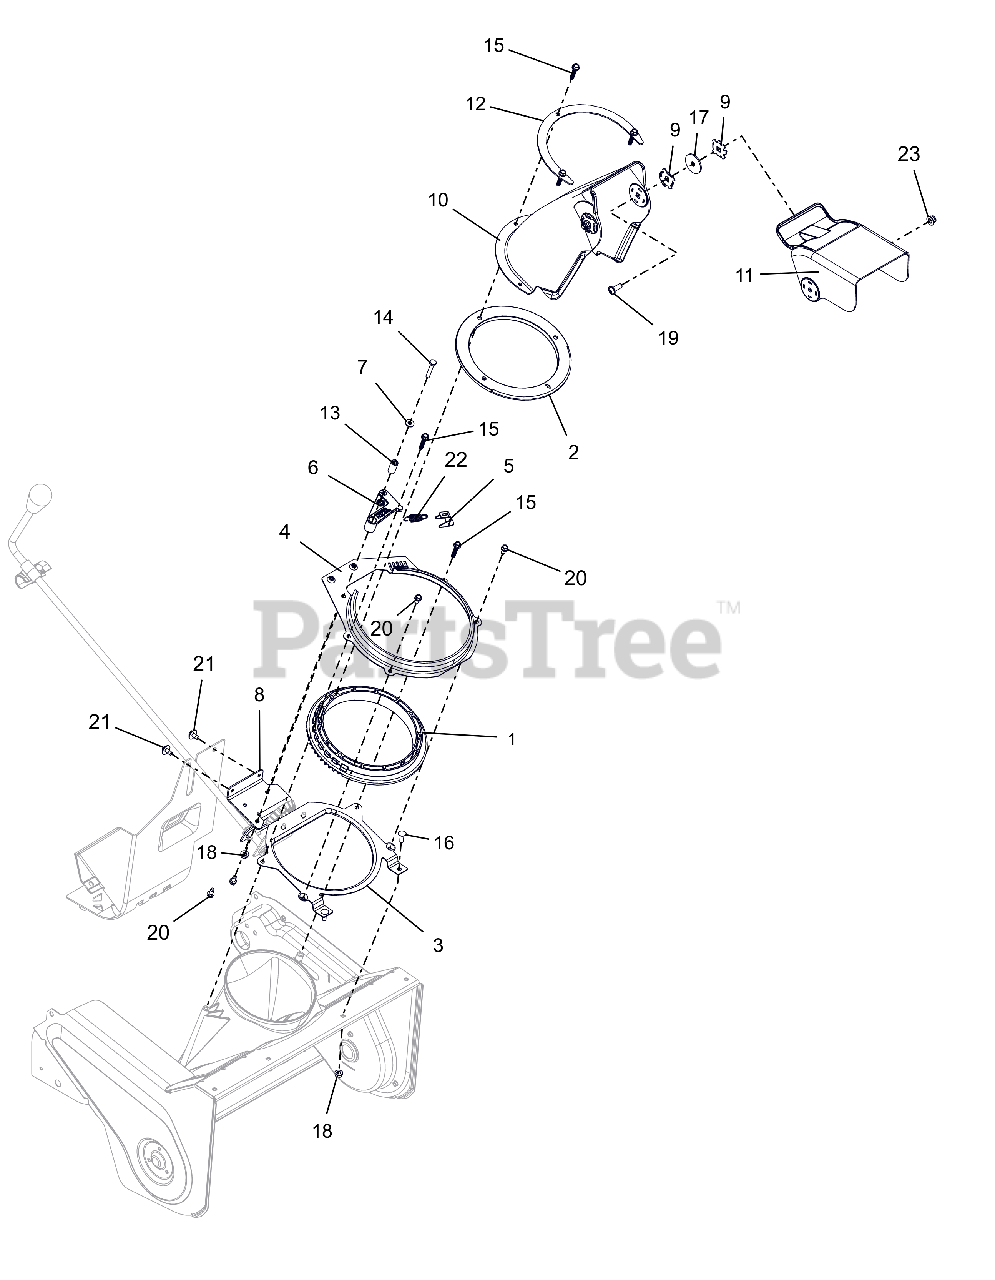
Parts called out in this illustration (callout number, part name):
1	GEAR, CHUTE RING
2	GUARD, WATER
3	RING, CHUTE MOUNT - LOWER
4	RING, CHUTE MOUNT - UPPER
5	BRKT, SPRG
6	ARM, PAWL
7	@WSHR-FL-STL.281X.62X.065 YWZC
8	BRKT, CHUTE ROTATION - REAR
9	PLATE, FRICTION
10	CHUTE,DISCHARGE - SINGLE STAGE
11	CAP, CHUTE - W/DECAL
12	BRKT, ROTATION - MANUAL
13	BSHG, SLV .265X.505X.995
14	@BLT-HEX .25-20X1.50 GR5 YWZC
15	SCR-TAP .25-10X1.25 HWH YWZC
16	@BLT-RDHDSQNK .25-20X.75 G5YZ
17	WSHR,FRICTION-.332X1.525X.094
18	@NUT-LK-TOP-FLG .25-20 YWZC
19	SCR,BTN-FLG .31-18X0.875
20	SCR-TAP .25-20X.50 HWH TR YWZ
21	SCR-TAP .25-20X.50 LGHWH TR YZ
22	SPRG, TENSION .052X.520X1.74
23	@NUT-LK-NYL-FLG .31-18 YWZC
